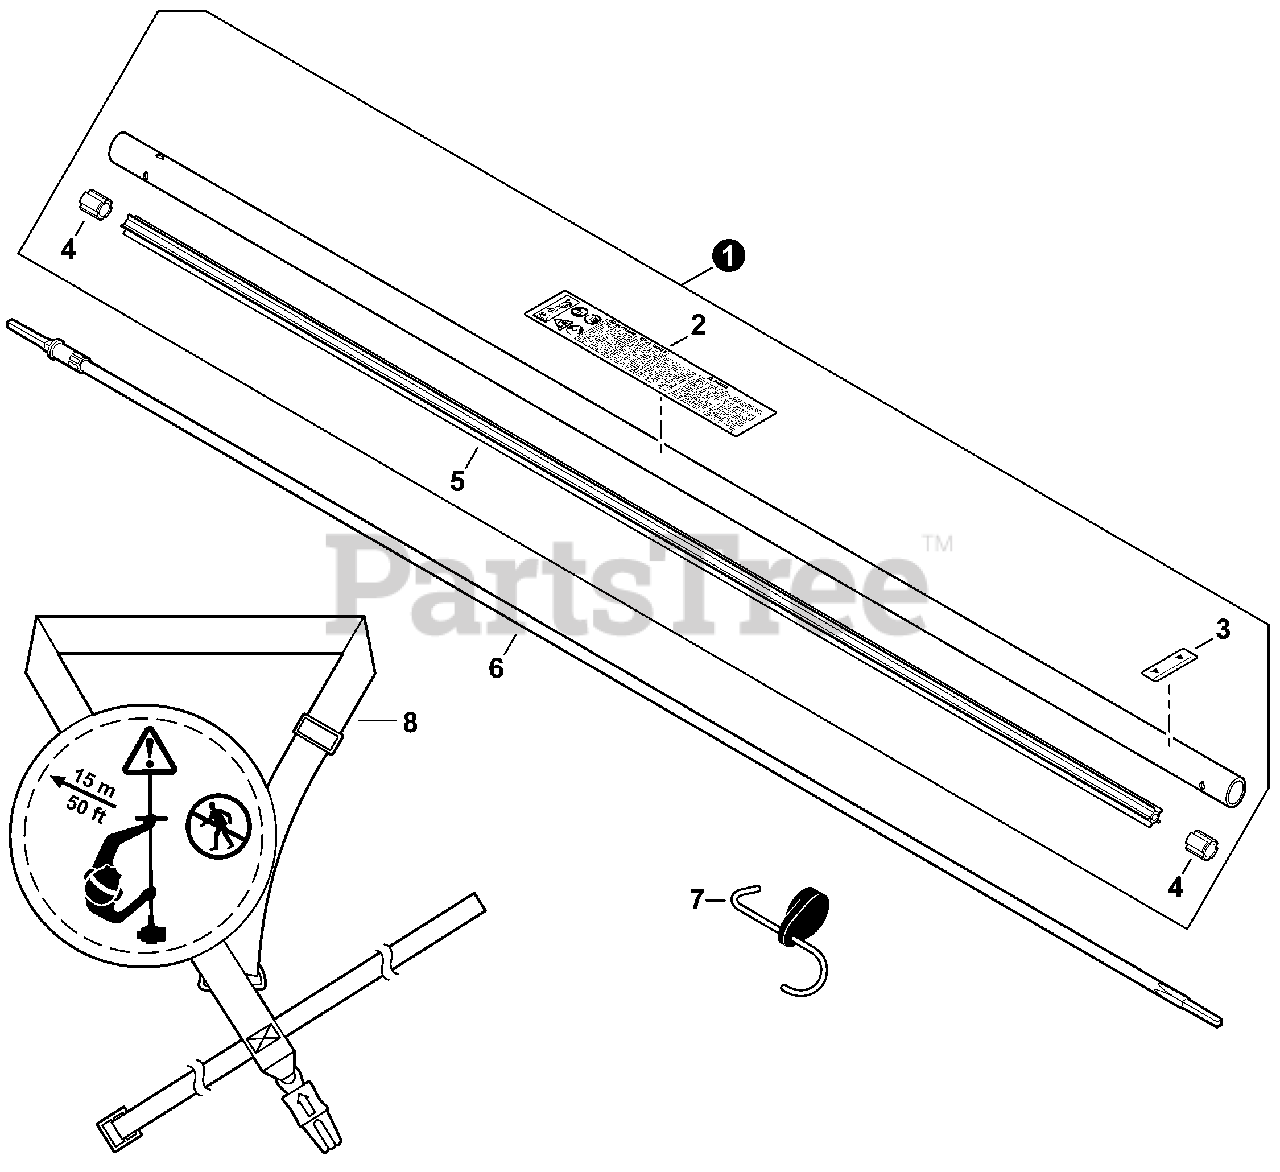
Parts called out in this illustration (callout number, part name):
1	MAIN PIPE ASSY
2	LABEL, CAUTION
3	LABEL - ALIGNMENT
5	LINER - FLEXIBLE
6	DRIVESHAFT - FLEXIBLE
7	HANGER, ATTACHMENT
8	HARNESS, SHOULDER
